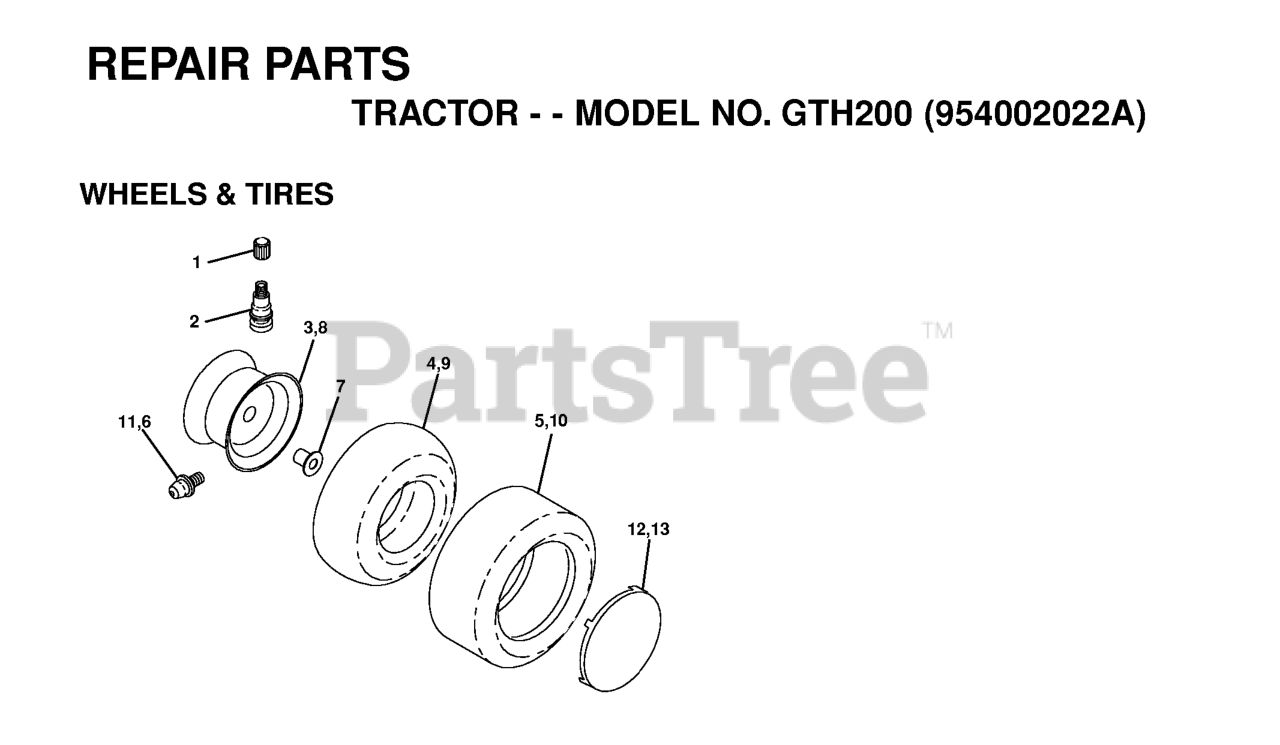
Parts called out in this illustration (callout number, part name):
2	VALVE STEM LT
3	RIM ASSY-FRONT
4	TUBE.16X6.5/7.5-8
5	TIRE HEAVY DUTY
6	FITTING LT
7	BEARING T
8	RIM.ASM.12X7.REAR.WHITE
9	TUBE.23X9.5-12
10	TIRE HEAVY DUTY
11	ZERK FITTING M
12	CAP,HUB REAR
13	COVER,WHEEL
